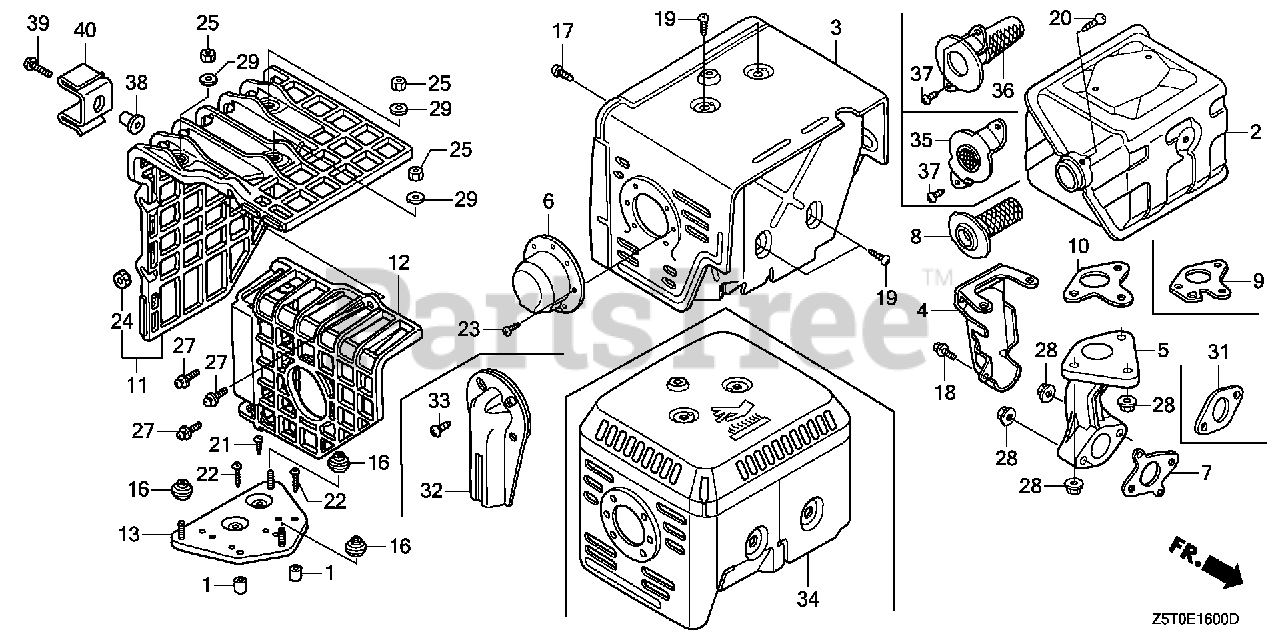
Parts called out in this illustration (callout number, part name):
2	MUFFLER
7	GASKET, EX. PIPE
9	GASKET, MUFFLER (ARRESTER) (NIPPON LEAKLESS)
10	GASKET, MUFFLER (NIPPON LEAKLESS)
10	GASKET, MUFFLER (THAI LEAKLESS)
17	SCREW, TAPPING (6X10)
19	SCREW, TAPPING (5X8)
28	NUT, FLANGE (8MM)
34	PROTECTOR, MUFFLER
35	FLANGE, BAFFLE
36	ARRESTER, SPARK
37	SCREW, TAPPING (5X8)
